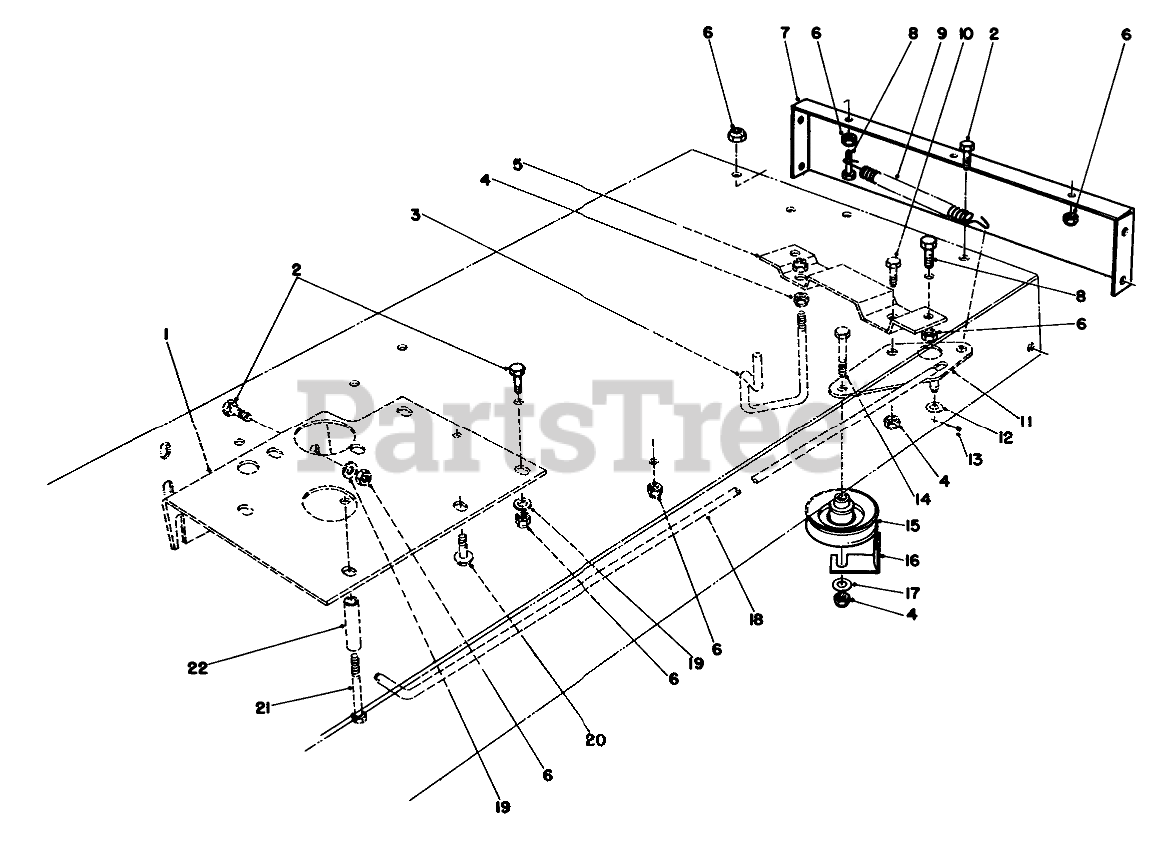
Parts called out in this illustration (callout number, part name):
1	REINF PLATE R
2	SCREW-HH
3	BELT GUIDE
4	NUT-LOCK, CONE
5	Bracket-Traction Support
6	NUT-LOCK, CONE
7	REAR FRAME R
8	SCREW-HH
9	TRACTION SPRING
10	SCREW-HH
11	Bracket-Traction Pivot
12	WASHER-FLAT
13	PIN-COTTER
14	SCREW-HH
15	PULLEY-IDLER
16	RETAINER-BELT
17	WASHER-FLAT
18	TRACTION ROD
19	WASHER-PLAIN
20	Screw-HH
21	SCREW-HH
22	OUTER TUBE SPACER
